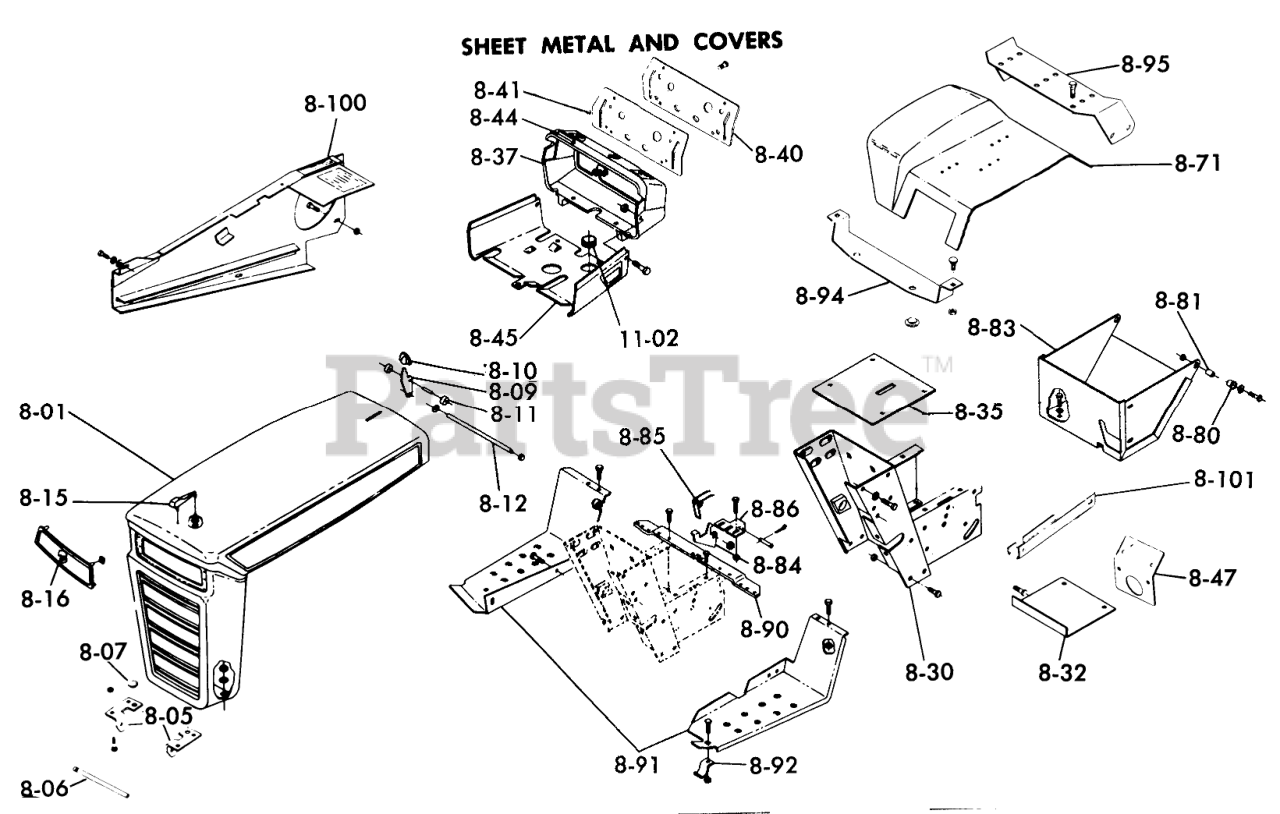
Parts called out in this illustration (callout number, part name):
8-01	Hood
8-05	GRILL PIVOT BRKT
8-05	Bracket-Grille-L.H.
8-05	Bolt
8-05	Nut
8-06	GRILL PIVOT ROD
8-06	E Ring-3/8
8-06	ROD-HOOD STOP
8-06	Cotter Pin
8-09	LEVER HOOD LATCH
8-09	SPIROL PIN
8-10	KNOB
8-11	Roller
8-12	Rod Latch
8-12	SPEED NUT
8-15	Hood Ornament
8-15	SPEED NUT
8-15	WASHER
8-30	Hoodstand Assembly
8-30	BOLT
8-30	Nut
8-30	Bushing
8-32	Cover-Dust
8-32	Bolt
8-32	Nut
8-35	Cover Plate
8-35	Screw
8-37	Housing
8-37	Screw
8-37	Nut
8-40	Dash Panel
8-40	PLUG BUTTON
8-41	BACK UP PLATE
8-41	SPEED NUT
8-41	SCREW BLACK
8-44	Tape
8-45	Support-Tank
8-45	Screw
8-45	SPEED CLIP
8-45	Plug Button
8-47	Instrument Backet
8-47	Screw
8-71	FENDER R
8-80	BUSHING-FLANGED
8-81	SPACER
8-81	Bolt
8-81	NUT
8-81	Washer
8-83	Tool Box
8-83	Bolt
8-83	LOCKWASHER
8-84	Fender Latch
8-85	Spring
8-85	NYLINER BUSHING
8-85	Pin
8-85	Cotter Pin
8-86	BRACKET FENDER LATCH
8-86	H H C S
8-86	Nut
8-90	Bracket-Footrest
8-90	SCREW
8-90	Bracket
8-91	Footrest-RH
8-91	Footrest-L.H.
8-91	Front Belt Guide
8-91	Footrest Pad-L.H.
8-91	Bolt
8-91	Nut
8-91	Screw
8-92	BRACKET
8-92	Bolt
8-92	Nut
8-94	Fender Bracket
8-94	CARRIAGE BOLT -4
8-94	Nut
8-94	GROMMET
8-95	Bracket Fender Hinge
8-95	BOLT
8-100	Belt Guard
8-100	H H C S
8-100	Screw
8-100	LOCKWASHER
8-100	Bolt
8-100	Nut
8-100	WASHER 5/16 SAE
8-101	Channel
8-101	Spacer
8-101	Lockwasher
8-101	Bolt
8-101	Nut
